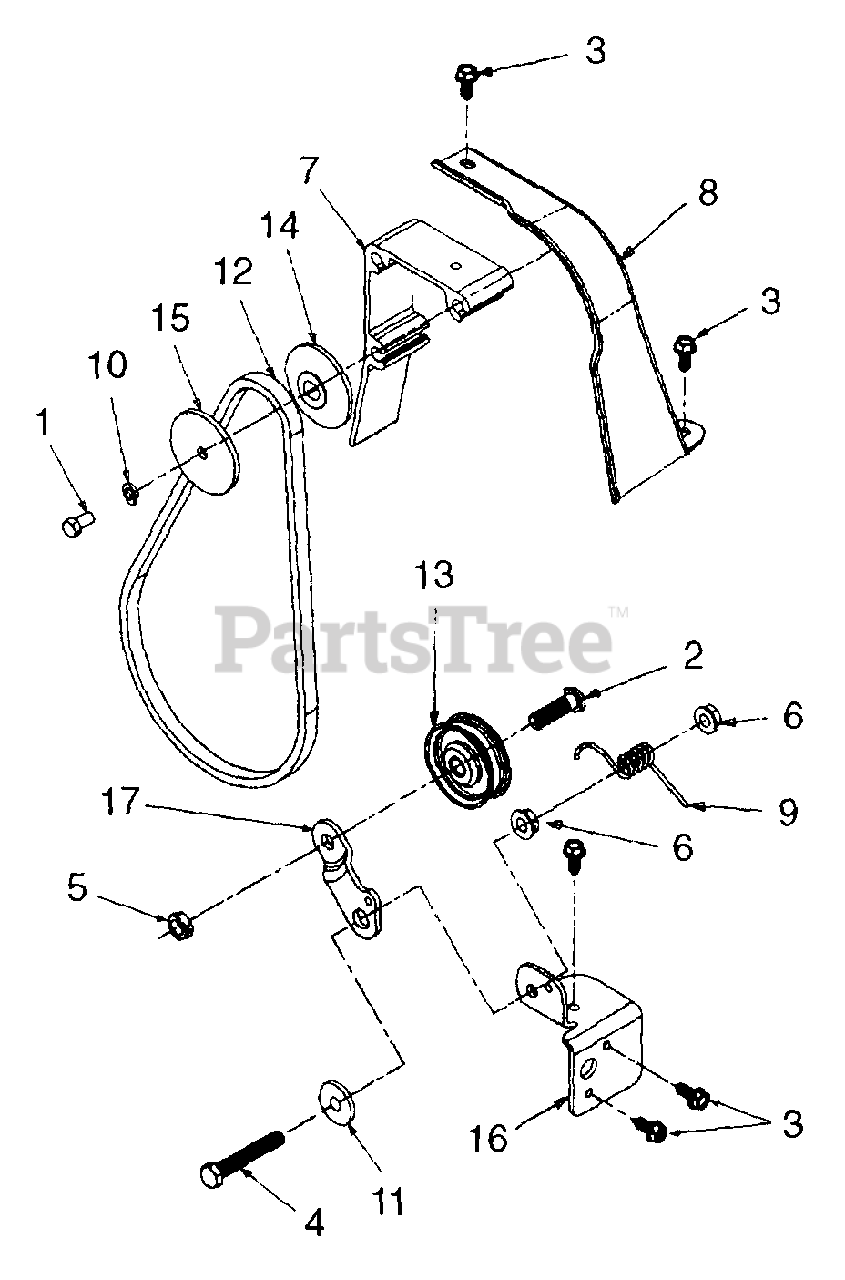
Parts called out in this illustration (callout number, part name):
1	Screw, Hex Cap, 1/4-28 x .50
2	Screw, Hex Cap, 3/8-16 x 1.25
3	Screw, Hex Wash Hd Tapp. 1/4-14 x .625
4	Screw, Hex Cap, 5/16-18 x 2.0
5	Nut, Hex Cent-L Jam, 3/8-16
6	Nut, Hex Flange Lock, 5/16-18
7	Adapter, Engine Mtg
10	Washer, Lock, 1/4
11	Shoulder Spacer, .50 ID x .27 L
12	V-Belt, 3/8 x 29.0 Lg
13	Pulley, Flat Idler
14	Pulley Half, 2.0 Dia.
15	Pulley Half, 2.0 Dia.
16	Bracket, Idler Pivot
17	Bracket, Idler
